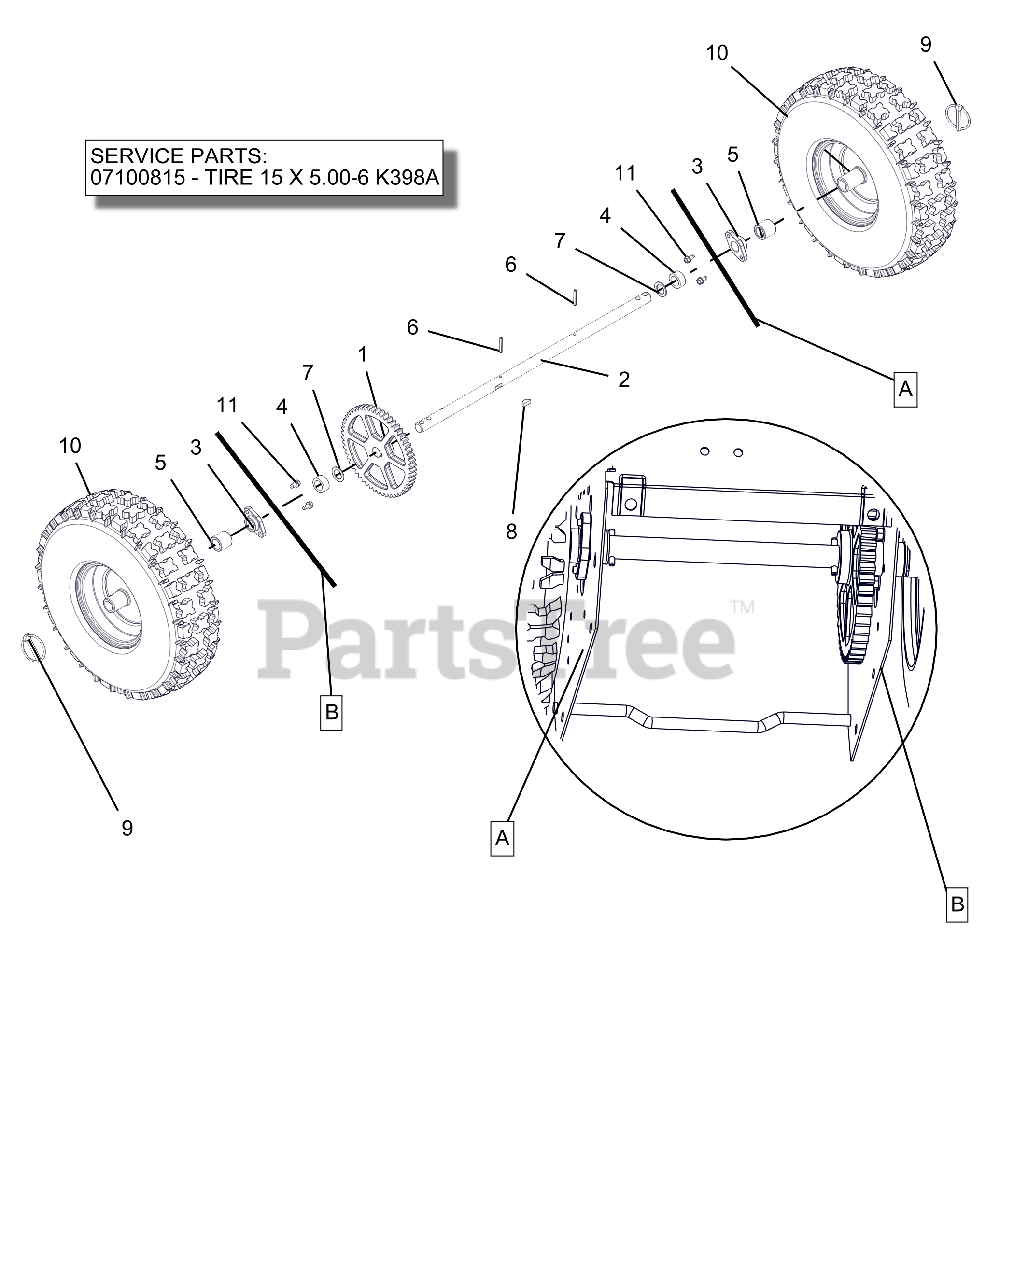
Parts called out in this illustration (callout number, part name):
1	SPUR GEAR, 54T .75ID X 6.75PD
2	AXLE, COMPACT 920,XXX 15" TIRE
3	BSHG .75X1.125X.65
4	BSHG-SLV .766 X 1.125 X .500
5	BSHG-SLV .75X1.12X1.062 NYL BK
6	PIN-ROLL .188X1.25
7	WSHR-FL-STL.754X1.125X.062YWZC
8	KEY-WDRF .25X.750X.313 SAE91
9	PIN-LOK .31X1.75
10	TIRE/WHEEL, 15X5.00-6 K398A
10	TIRE, 15" K398A
11	SCR-TAP .25-20X.50 HWH TR YWZ
